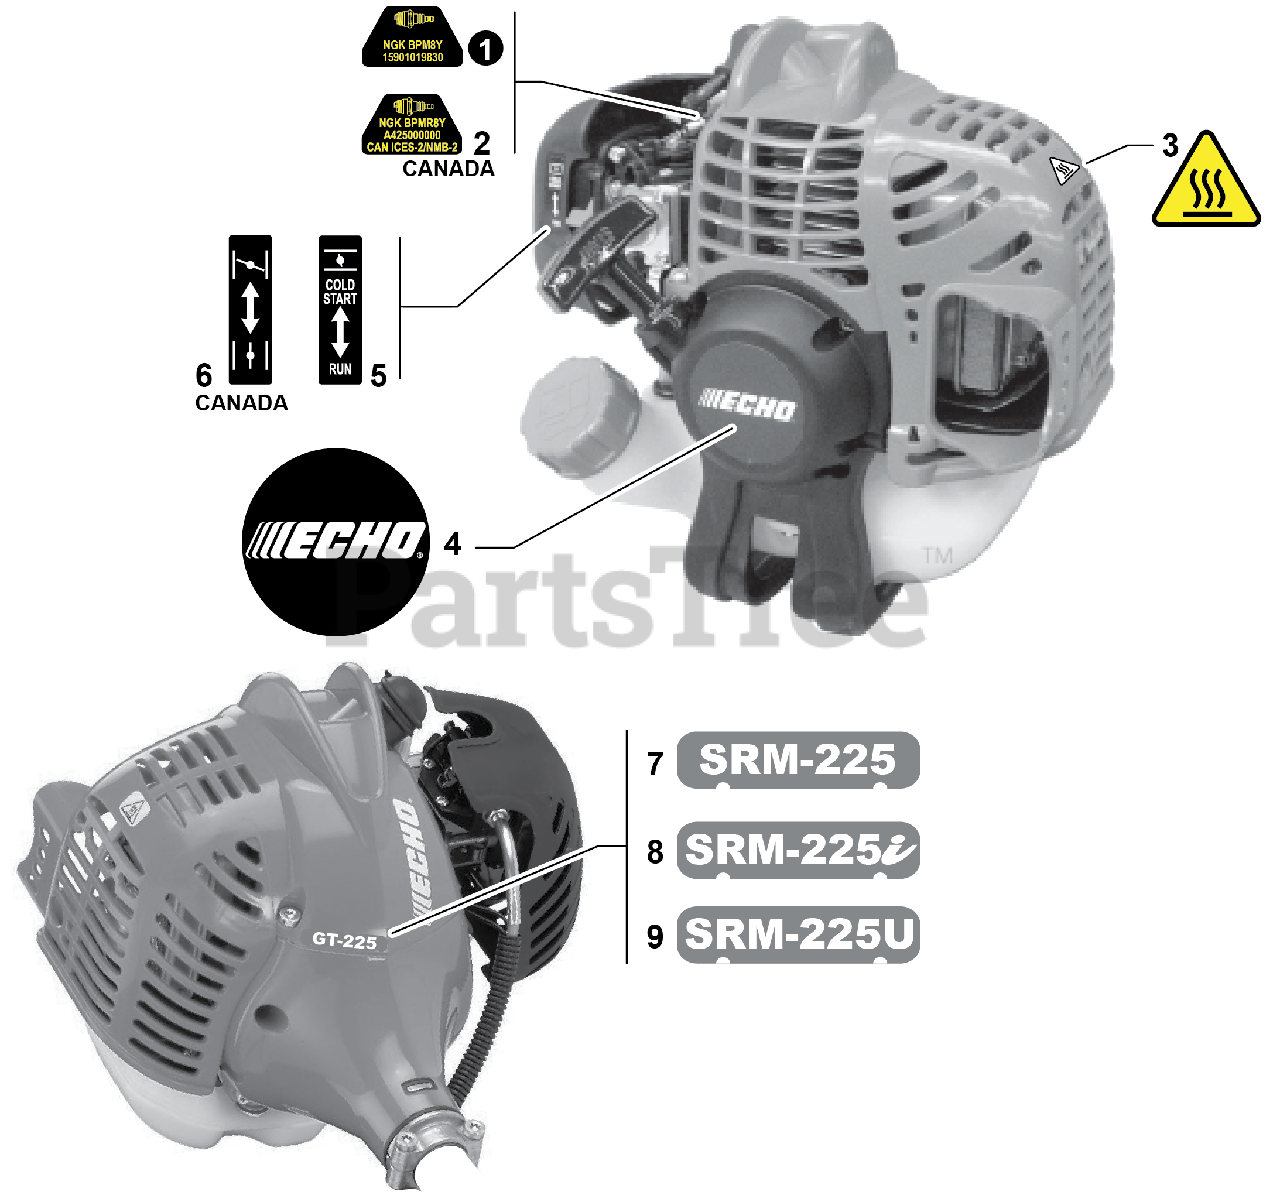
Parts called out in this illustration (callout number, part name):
1	LABEL, SPARK PLUG - BPM8Y
2	LABEL, SPARK PLUG - BPMR8Y
3	LABEL, CAUTION - HOT
4	LABEL, RECOIL STARTER
5	LABEL, CHOKE
6	LABEL, CHOKE
7	LABEL, MODEL SRM-225
8	LABEL, MODEL SRM-225I
9	LABEL, MODEL SRM-225U
